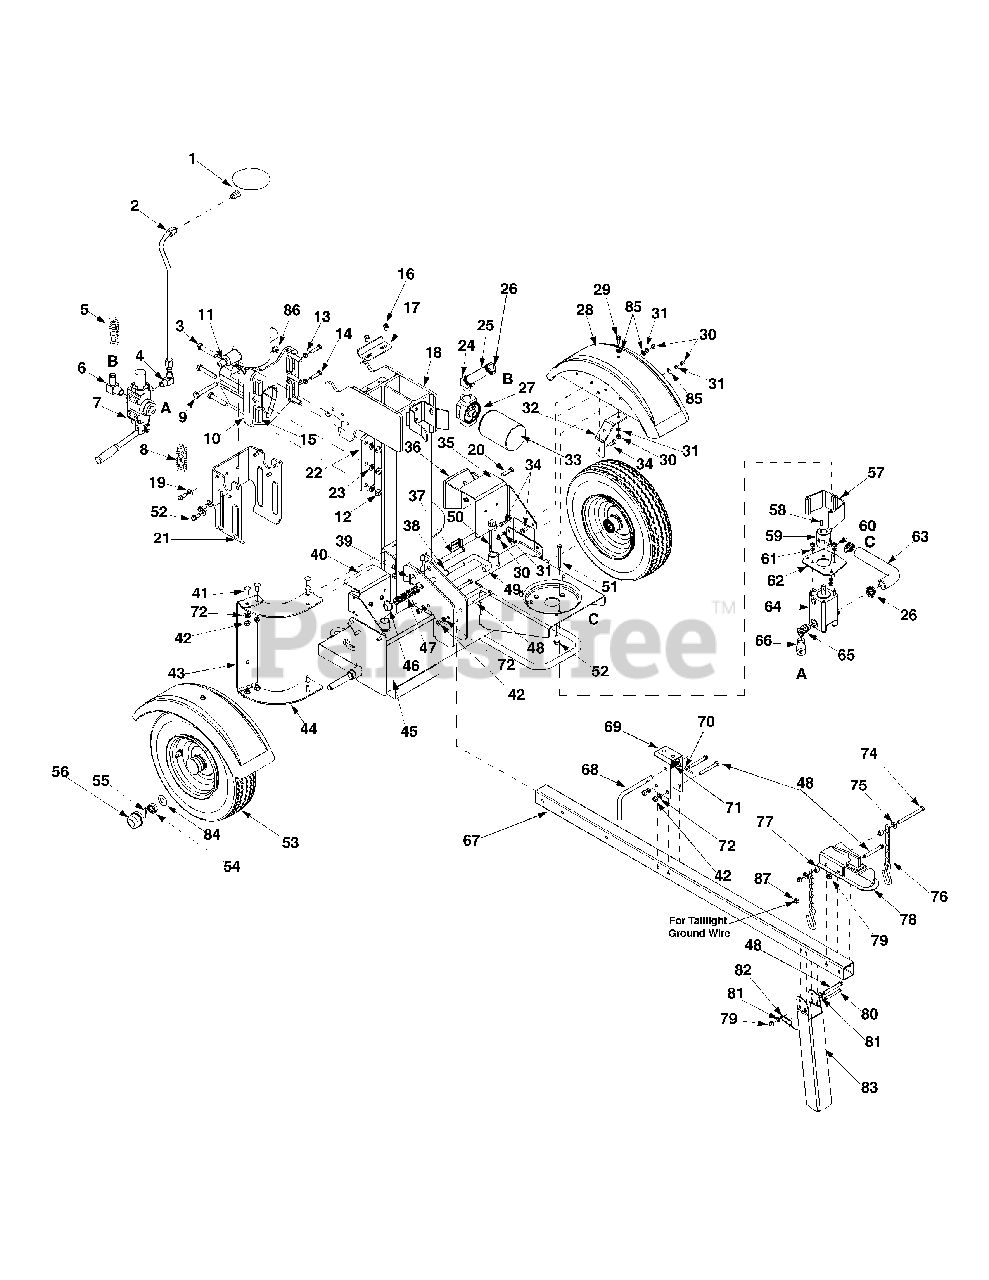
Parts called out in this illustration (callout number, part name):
1	Hydraulic Cylinder 718-0769A
1	Kit Seal 4.5" for XINGHUI cylinder 718-0769A
1	Kit Seal 4.5" for ENERGY cylinder 718-0769A
2	Hydraulic Tube
3	Hex Cap Screw 1/2-20 x 2.75
4	90° Solid Adapter
5	Flat Washer, .434 x .880 x .062
6	Return Elbow
7	Control Valve
8	Lock Washer, 5/16
9	Hex Cap Screw 1/2-13 x 3.25
10	Wedge Assembly
11	Nipple Pipe 1/2-14
12	Lock Nut 1/2-20
13	Hex Jam Nut 3/8-24
14	Hex Cap Screw 3/8-24 x 1.5
15	Adjustable Gib
16	Screw 5/16-18 x.75
17	Cylinder Support Bracket
18	Beam Assembly
19	Flat Washer.406 ID x.875 OD
20	Hex Washer Screw 3/8-16 x 1.0
21	Dislodger
22	Back Plate
23	Lock Washer 1/2
24	Adapter 3/4-14
25	Return Hose 3/4" ID x 44"
26	Hose Clamp 5/8"
27	Filter Housing
28	Hex Screw, 5/16-18 x 1.25
29	Hex Screw , 5/16-18 x 1.0
30	Hex Flange Nut, Nylon, 5/16-18
31	Flat Washer.760 ID x.500 OD
32	Hex Bolt 5/16-18 x 3.25"
33	Oil Filter
35	Mounting Bracket, Fender
36	Hex Screw, 5/16-18 x .875
38	Flat Washer.635 ID x.93 OD
39	Cotter Pin
40	Fender, Black
41	Carriage Bolt 3/8-16 x 1.0
42	Hex Nut 3/8-16
44	Log Tray Bracket
45	Frame Assembly
47	Compression Spring
48	Hex Bolt 3/8-16 x 3.25"
50	Vented Dipstick
51	Hex Screw 5/16-24 x 3.25
53	Wheel Assembly
53	Cone Bearing
53	Grease Retainer
54	Slotted Nut 3/4-16
57	Coupling Shield
58	Square Key 3/16" x.75
59	Flexible Coupling
61	Jack Stand
62	Rear Coupling Support Bracket
66	High Pressure Hydraulic Hose
67	Tongue Tube Assembly
68	Tongue Latch Rod
70	Spiral Pin
71	Compression Spring
72	L-Washer 3/8"
73	Hex Lock Nut 1/2-13
74	Hex Cap Screw 3/8-16 x 4.25
75	Flat Washer.385 ID x.870 OD
77	Spacer.375 ID x.625 OD
78	Hitch Coupler
79	Hex Lock Nut 3/8-16
81	Flat Washer.375 ID x.738 OD
83	Hex Screw, 5/16-18 x .875
84	Hex Nut, 5/16-18
86	Light Bracket, LH
87	Light Bracket, RH
